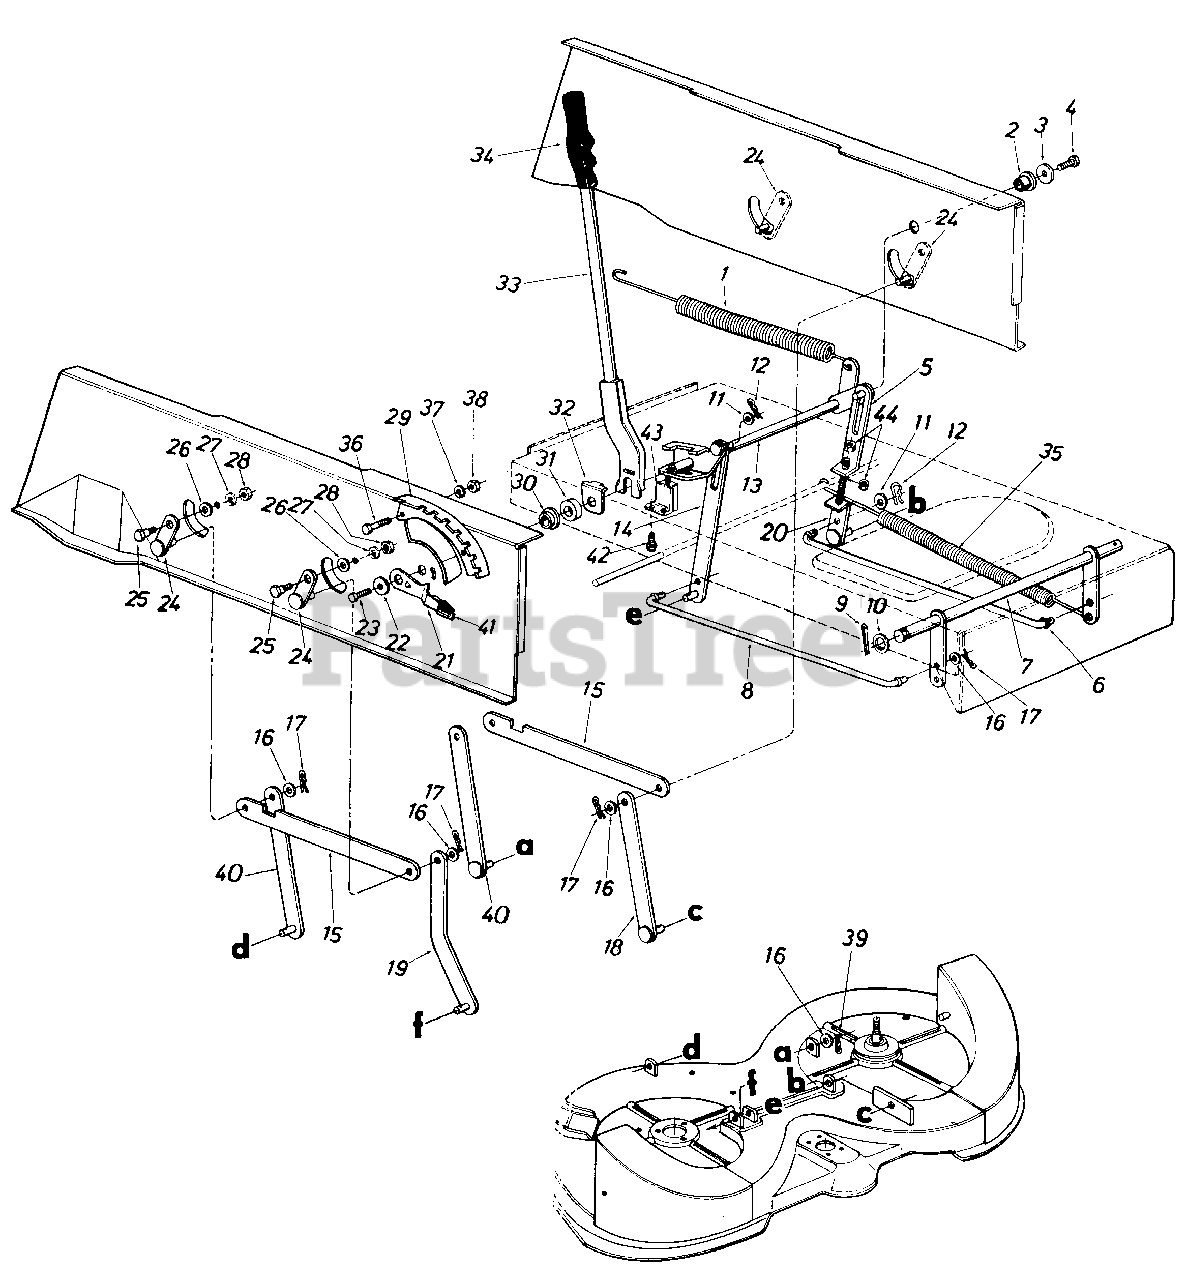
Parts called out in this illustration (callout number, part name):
1	Extension Spring .99" O.D. x 11.00" Lg.
2	Flange Bearing .634" I.D.
3	Fl-Wash. .344" I.D. x 1.125" O.D. x .125
4	Hex Wash. Hd. Self-Tap Scr. 5/16-18 x .62" Lg.
5	Adj. Link Lift
6	Stabilizer Rod
7	Stabilizer Shaf t Ass'y.
8	Stabilizer Rod
9	Cotter Pin 1/8" Dia. x 11/4" Lg.
10	Fl-Wash .635" I.D. x 1.12" O.D.
11	Fl-Wash. .531" I.D. x .940" O.D.
12	Inter. Cotter Pin .50" Dia.
15	Connecting Rod
16	Fl-Wash. .40" I.D. x .88" O.D.
17	Inter. Cotter Pin For 3/8" Rod
18	Link Deck Hanger Ass'y.
19	Link Deck Hanger Ass'y.
20	Adj. Link Lift Ass'y.
21	Deck Lift Down Stop.
22	Fl-Wash. .344" I.D. x 1.125n O.D. x .125
23	Hex Wash. Hd. Self-Tap Scr. 5/16-18 x .62" Lg.
24	Pivot Link Ass'y.
25	Shld. Bolt .437" Dia. x .180" Lg. (5/16-18)
26	Fl-Wash. .344" I.D. x .62" O.D.
27	L-Wash. 5/16" I.D.
28	Hex Nut 5/16-18 Thd.
29	Index Brk't.
30	Flange Wash. .628" I.D. x 1.25" O.D.
31	Rubber Wash. 1.50" O.D. x .63" I.D. x .60
32	Retainer Washer Lift Handle
33	Lift Handle Ass'y.
34	Grip
35	Extension Spring .99" O.D. x 13.25" Lg.
36	Hex Bolt 5/16-18 x .75' Lg.
37	L-Wash. 5/16" I.D.
38	Hex Nut 5/16-18 Thd.
39	Inter. Cotter Pin
40	Link Deck Hanger Ass'y.
41	Knob
42	Hex AB-Tap Scr. #10 x .50" Lg.
43	Safety Switch
44	Hex Jam Nut 3/8-16 Thd.
